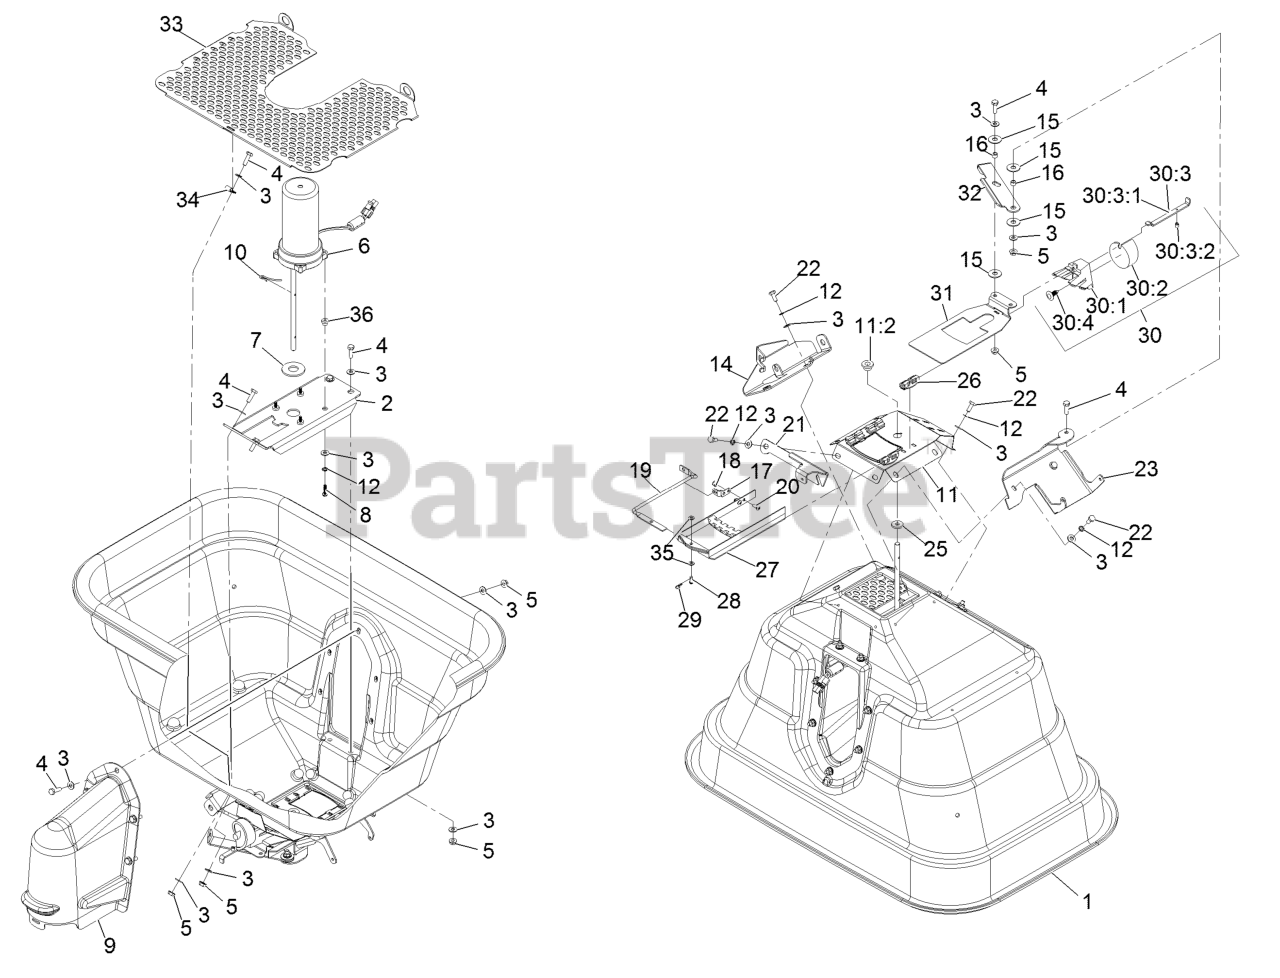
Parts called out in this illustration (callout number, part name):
2	BRACKET-MOUNT, MOTOR
3	WASHER-FLAT
4	SCREW-HH
6	SPREADER MOTOR ASM
8	SCREW-SHWH
9	COVER-MOTOR
10	AGITATOR
11	MULCH PLATE W/ BEARING AS
11:2	BEARING-BOTTOM, HOPPER
12	WASHER-LOCK, INT
14	BRACKET-HOPPER, GATE CONT
17	BRACKET-DIFFUSER
18	NUT-HEX
19	ROD-CONTROL, DIFFUSER
20	SCREW-PPH
21	BRACKET-SPRING, HOPPER DE
22	SCREW-HH
23	BRACKET-LEVER, HOPPER GAT
25	WASHER-FELT
26	GUIDE-RATE, GATE
27	DIFFUSER
28	PIN-CLEVIS
29	PIN-COTTER, HAIR
30	RATE DIAL ASM
30:1	MOUNT-DIAL
30:2	DIAL
30:3	Rate Gate Link ASM
30:3:1	LINK-GATE, RATE
30:3:2	SCREW-SHOULDER, SLOTTED
30:4	CLIP
31	GATE-RATE
32	LEVER-GATE
33	SCREEN-HOPPER, MEDIUM HOL
33	SCREEN-HOPPER, SMALL HOLE
33	SCREEN-HOPPER, LARGE HOLE
34	CLAMP-LOOP
35	WASHER-FLAT
